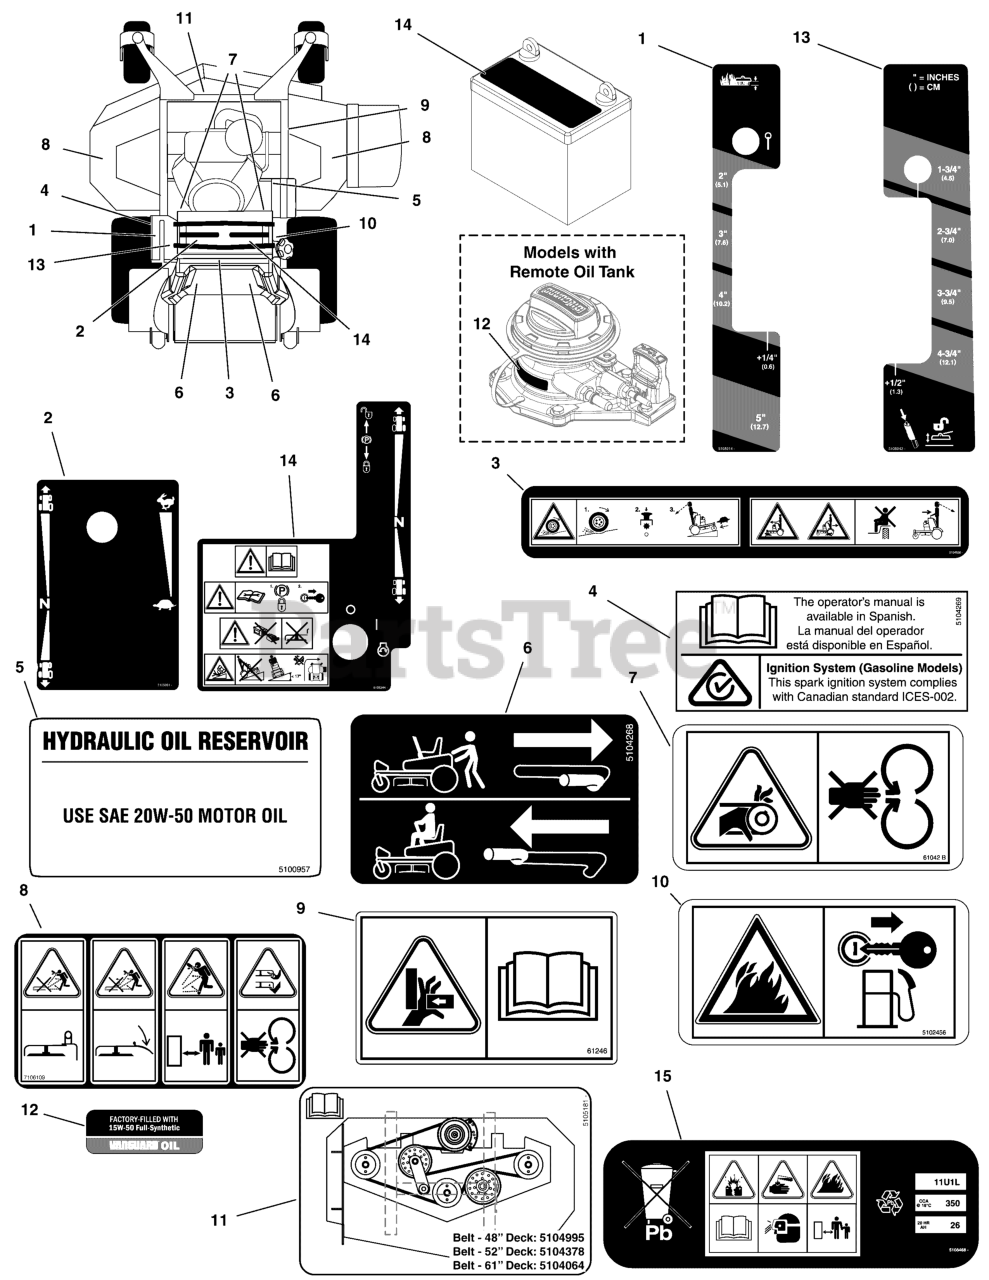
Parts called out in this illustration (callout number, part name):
1	DECAL, CUT HEIGHT, STAND ON
2	DECAL, DASH PANEL, LH, CONTROLS
3	DECAL, WARNINGS, OPER COMPARTMENT, CE
4	DECAL, SPANISH MANUAL, IGES, C-TICK
5	DECAL, HYDRAULIC OIL, SAE 20W50
6	DECAL, TRANSAXLE RELEASE, WB
7	DECAL, CE DANGER, HAND IN BELT
8	DECAL, DISCHARGE SAFETY, EXPORT
9	DECAL, Pinch Point, CE
10	DECAL, FIRE ANSI EXPORT
11	DECAL, BELT ROUTING, SRS-48-52-61
12	LABEL, OIL INFORMATION
13	DECAL, CUT HEIGHT, SRSZ2 & Z3
14	DECAL, DASH PANEL, RH, WRNGS/CNTRLS, CE
15	DECAL, BATTERY, EXP, 11U1L
